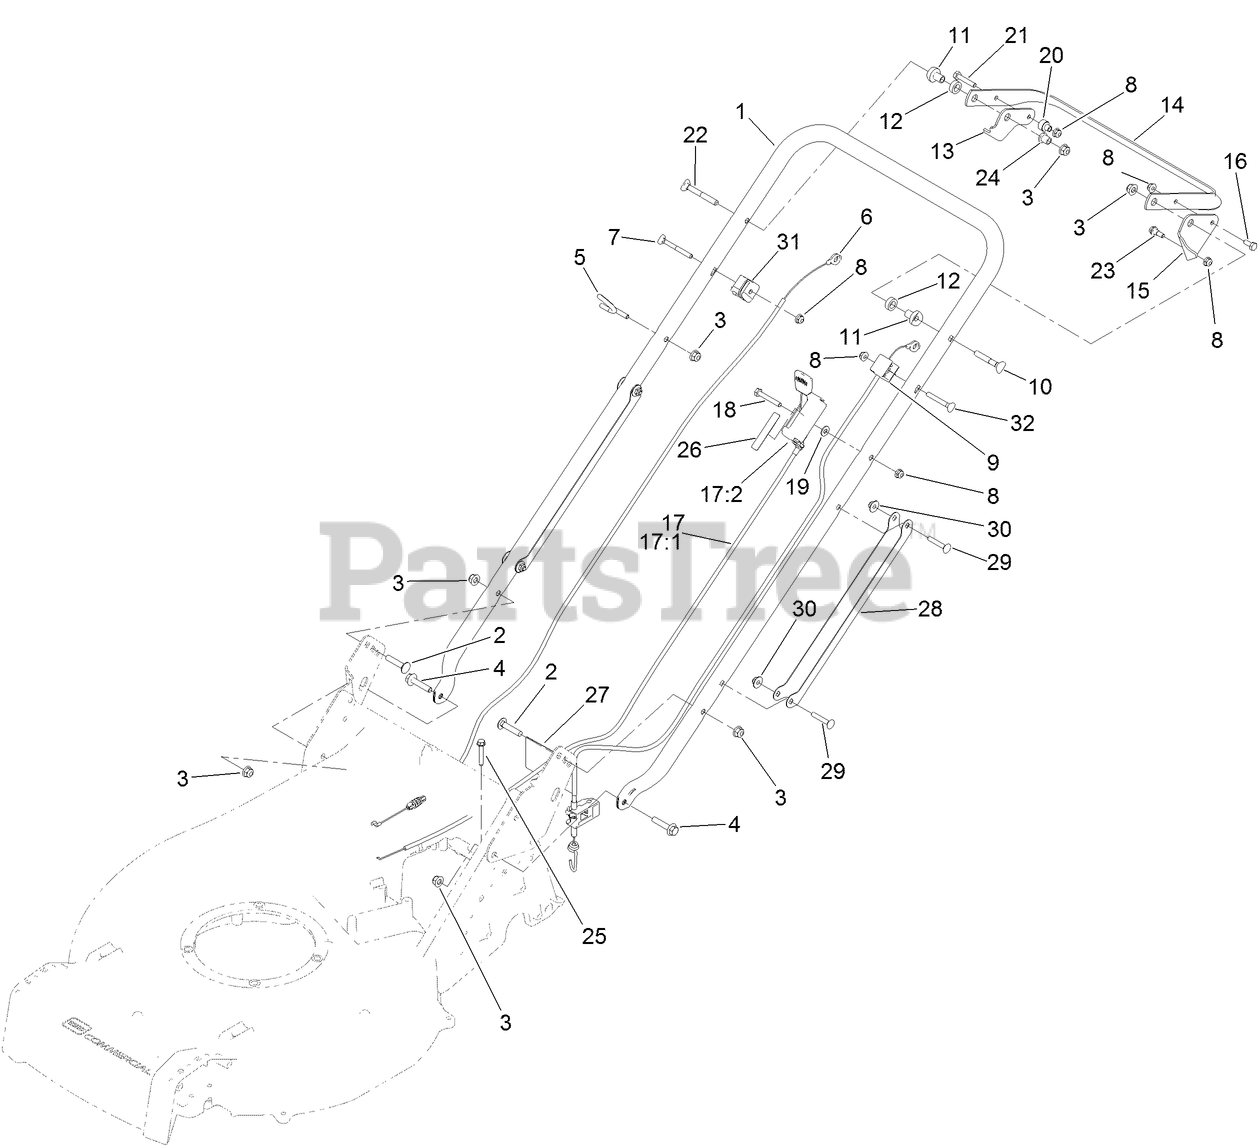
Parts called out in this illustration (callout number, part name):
2	BOLT-CARR
3	NUT-HF, NI
4	SCREW-HHF
5	GUIDE,ROPE
6	CABLE-BRAKE
7	SCREW-HANDLE
8	NUT-HF
9	CABLE-TRACTION
10	SCREW-HANDLE
11	SPACER-SUPPORT
12	SPACER-NYLON
13	LEVER-CONTROL, BRAKE
14	BAR-CONTROL, ZONE START
15	LEVER-CONTROL, TRACTION
16	SCREW-HH
17	CONTROL-THROTTLE/CHOKE
17:1	CABLE-THROTTLE
17:2	CONTROL-THROTTLE
18	SCREW-HH
19	WASHER-FLAT
20	SPACER-STEPPED
21	SCREW-HH
22	SCREW-HANDLE
23	BOLT-SHOULDER
24	SPACER
25	SCREW-HWH
26	DECAL-THROTTLE, CHOKE
28	GUARD-CABLE, HANDLE
29	SCREW-CARR
30	NUT-HF
31	ANCHOR-CABLE
32	SCREW
